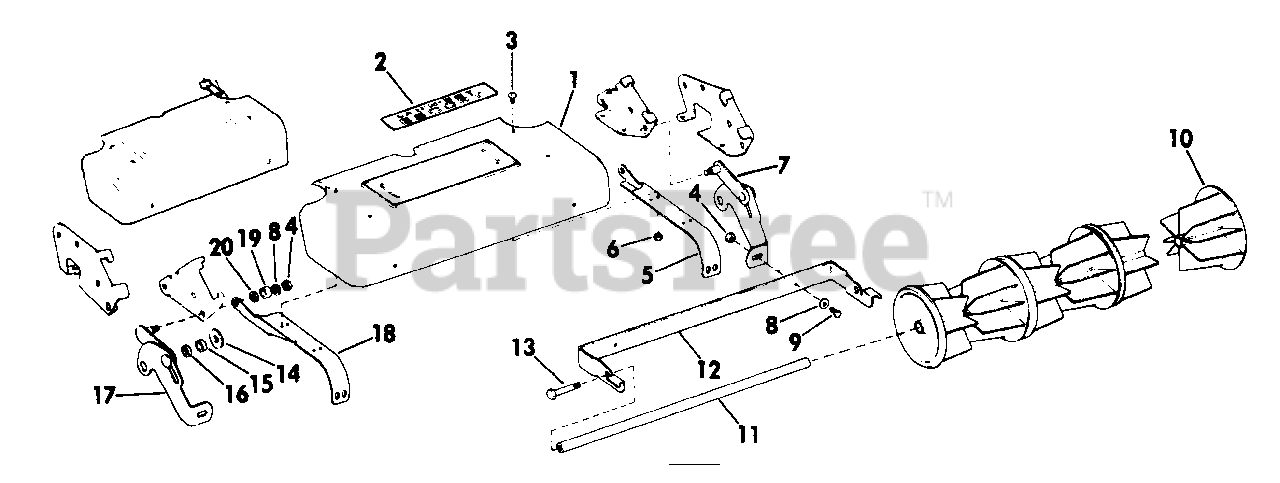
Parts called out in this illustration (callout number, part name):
1	Roller Cover & Decal Assembly
5	Cover Hinge-Right
7	Roller Link Assembly-Left
12	Carrier Strip
15	Spacer-Wheel-Red
16	Spacer-Wheel Bracket-Red
17	Roller Link Assembly-Right
18	Cover Hinge-Left
19	Spacer-Silver
20	Spacer-Hinge-Silver
